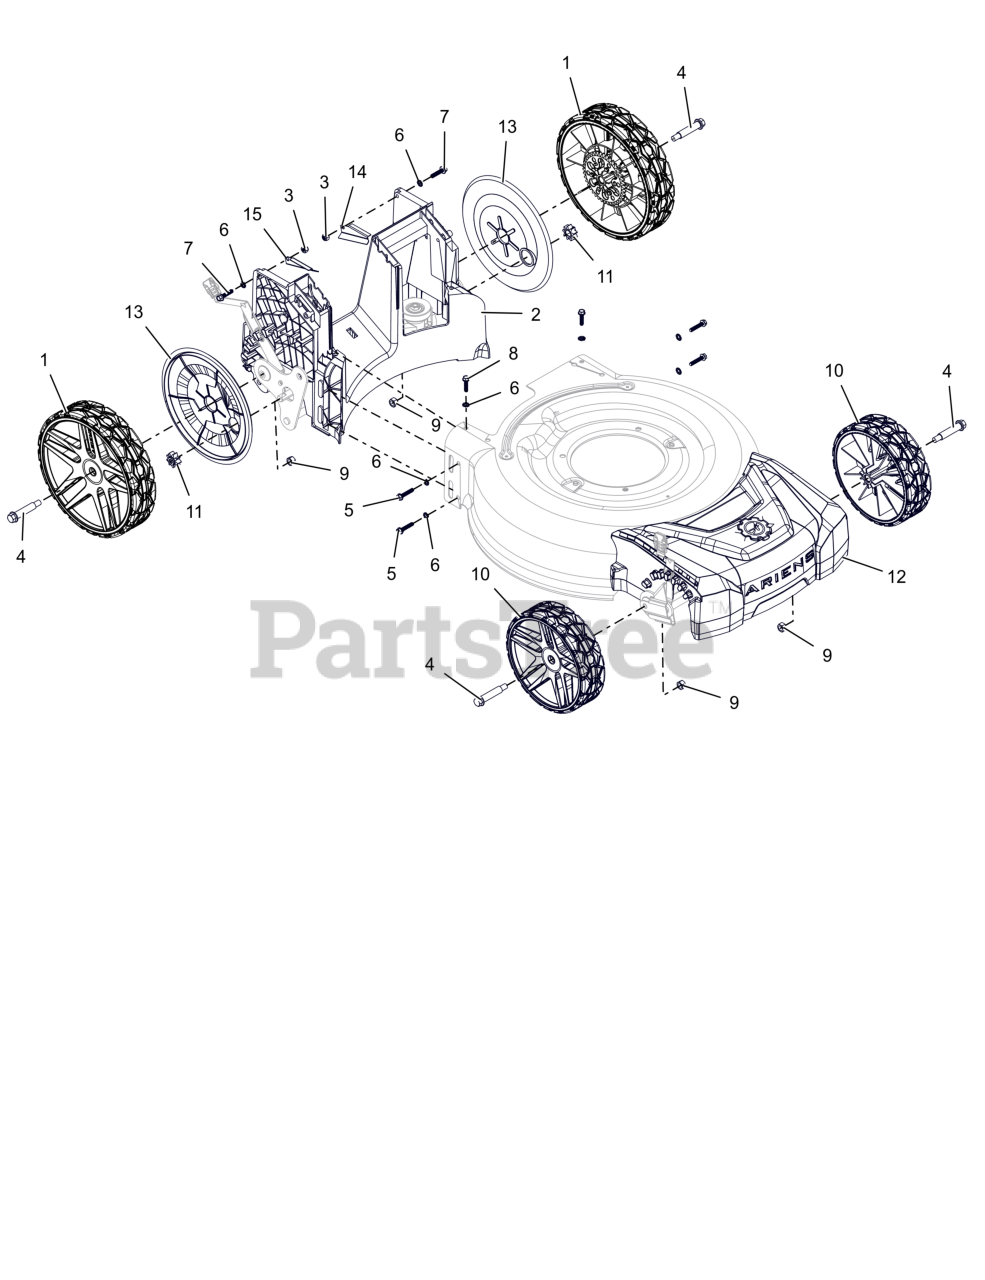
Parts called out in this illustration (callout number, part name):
1	ASM, WHEEL WITH GEAR - 10" PM
2	ASM, REAR BAFFLE-RWD
3	NUT, NYLOC 1/4-20
4	BLT, SHLDR HWH .325X1.981X 3/8-16
5	SCR, HI-LO HWH 1/4-15 X 1.25
6	WSHR-LK-EXT, .256X.510X.028
7	BLT, HEX 1/4-20 X 1.125
8	SCR, HI-LO HWH 1/4-15 X 1.00
9	NUT-JAM .375-16 HIGH STRENGTH
10	WHEEL, 8" - BLACK
11	GEAR, RWD SPUR
12	COVER, FRONT
13	COVER, DUST - 10"
14	BRKT, LH DOWNWARD (BLACK)
15	BRKT, RH DOWNWARD (BLACK)
